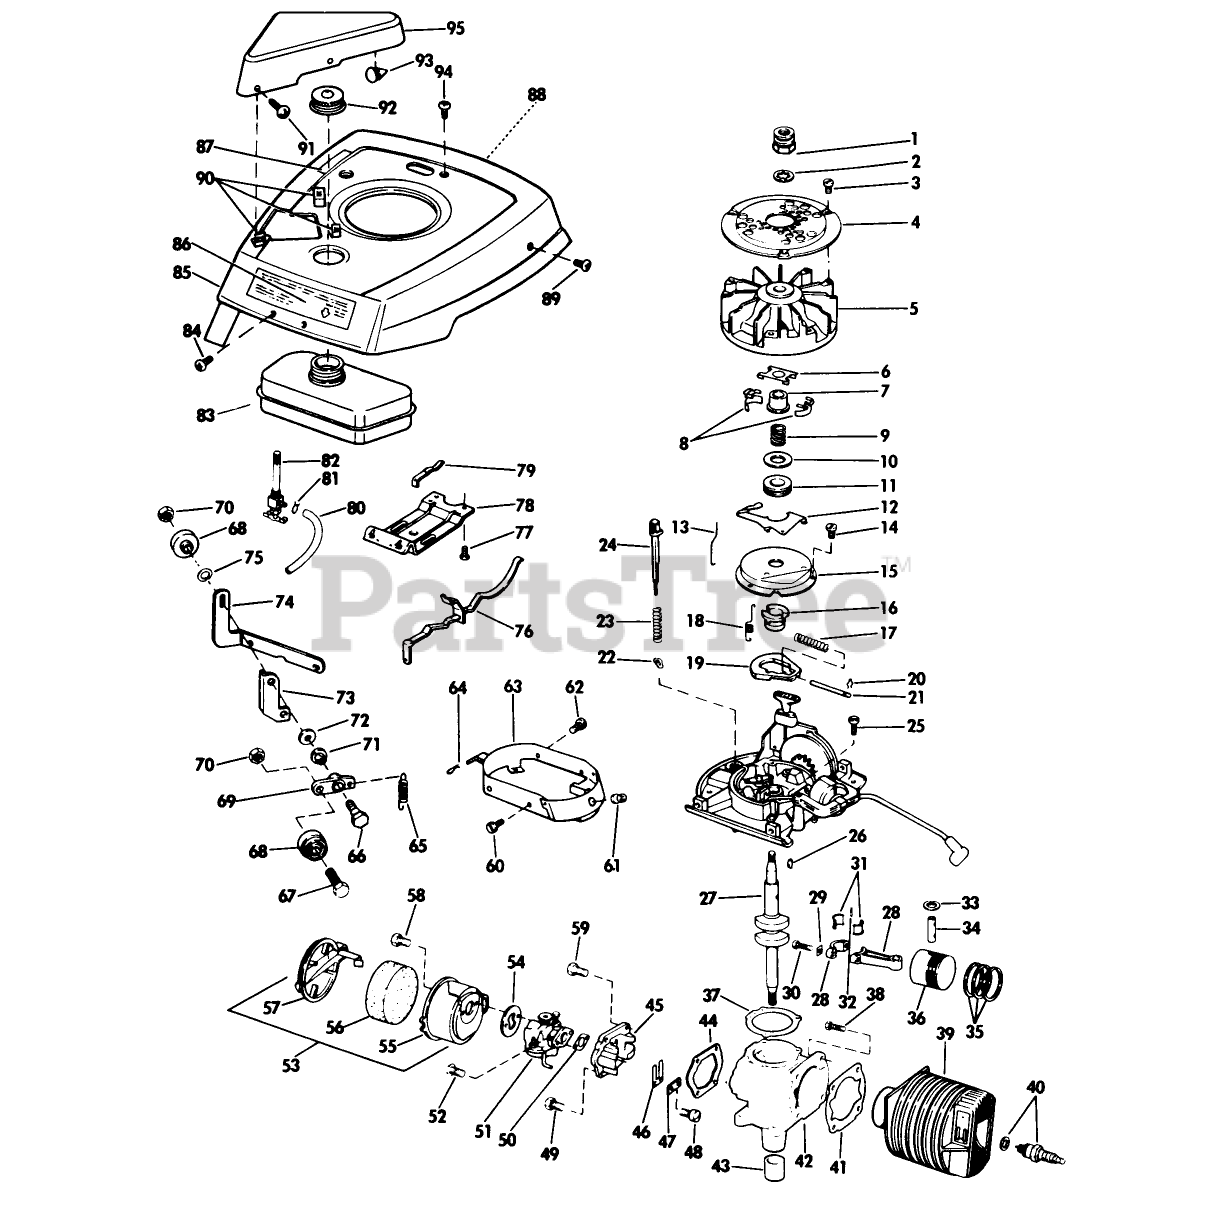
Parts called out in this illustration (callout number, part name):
7	COLLAR S
9	SPRING S
11	THRUST COLLAR S
12	LEVER-GOVERNOR S
14	SCREW S
15	DUST COVER S
16	SPARK ADV. S
17	SPARK ADV. SPRING S
19	FLYWEIGHT S
20	SPARK ADJ. SPRING
21	PIN,SPARK ADV. S
23	SPRING S
31	LINER ASM
33	RING-RETAINING
37	GASKET S
41	GASKET S
47	PLATE-BACKUP, REED
49	SCREW S
50	GASKET S
56	AIR FIL.ELEM S
58	SCREW S
59	SCREW S
60	SCREW S
61	NUT-CLIP
68	IDLER PULLEY
76	SPEED CONTROL
77	SCREW S
80	GAS LINE
81	CLAMP - HOSE S
82	VALVE&SCREEN SM
85	Engine Cover Assy.
89	SCREW S
94	SCREW F
